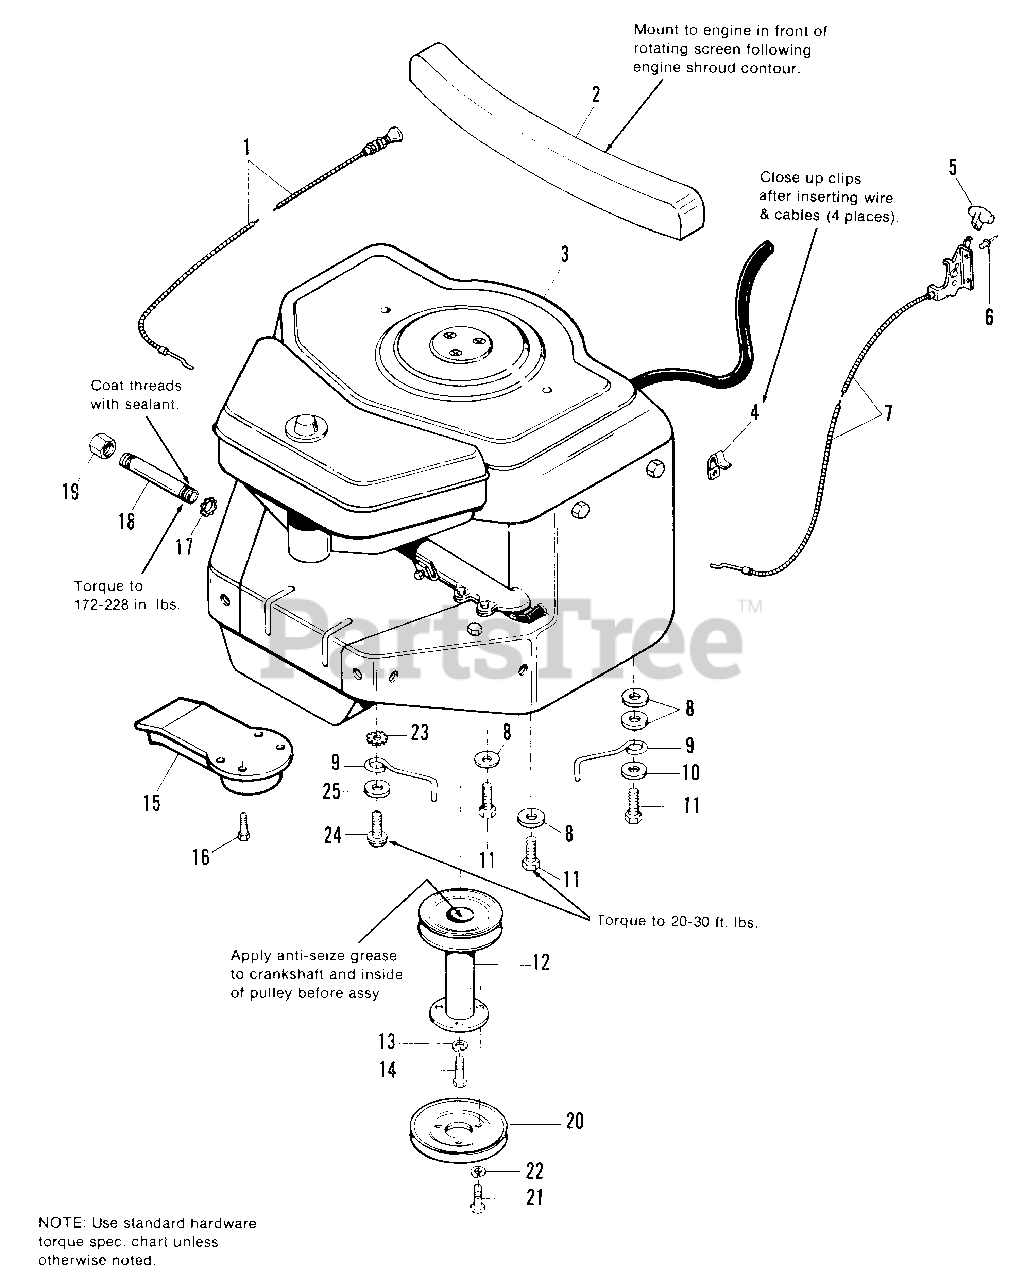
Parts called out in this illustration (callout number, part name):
1	CONTROL, Choke
2	BAFFLE, Engine, Rear
4	CLIP, Wire
5	KNOB, Throttle
6	RIVET, Pop, 1/4 x 7/16
7	CONTROL ASSY.
8	WASHER, Plain
9	STOP, Belt
10	WASHER, Plain, 3/8
11	SCREW, Taptite, 3/8-16 x 1-1/2
12	PULLEY ASSY., Engine
13	LOCKWASHER, 7/16
14	CAPSCREW, Hex, 7/16-20 x 1-1/4
15	EXTENSION ASSY., Muffler
16	SCREW, Hex Thd., Cutting, #8-32 x 3/8
17	LOCKNUT, Conduit
18	PIPE, Oil Drain
19	PIPE, Cap, Hex
21	CAPSCREW, Hex, 5/16-18 x 1-1/2
22	LOCKWASHER, 5/16
23	LOCKWASHER, Ext. Tooth, 3/8, Zinc Pltd.
24	SCREW, Taptite, 3/8-16 x 1-1/2, Zinc Pltd.
25	WASHER, 3/8, Zinc Pltd.
